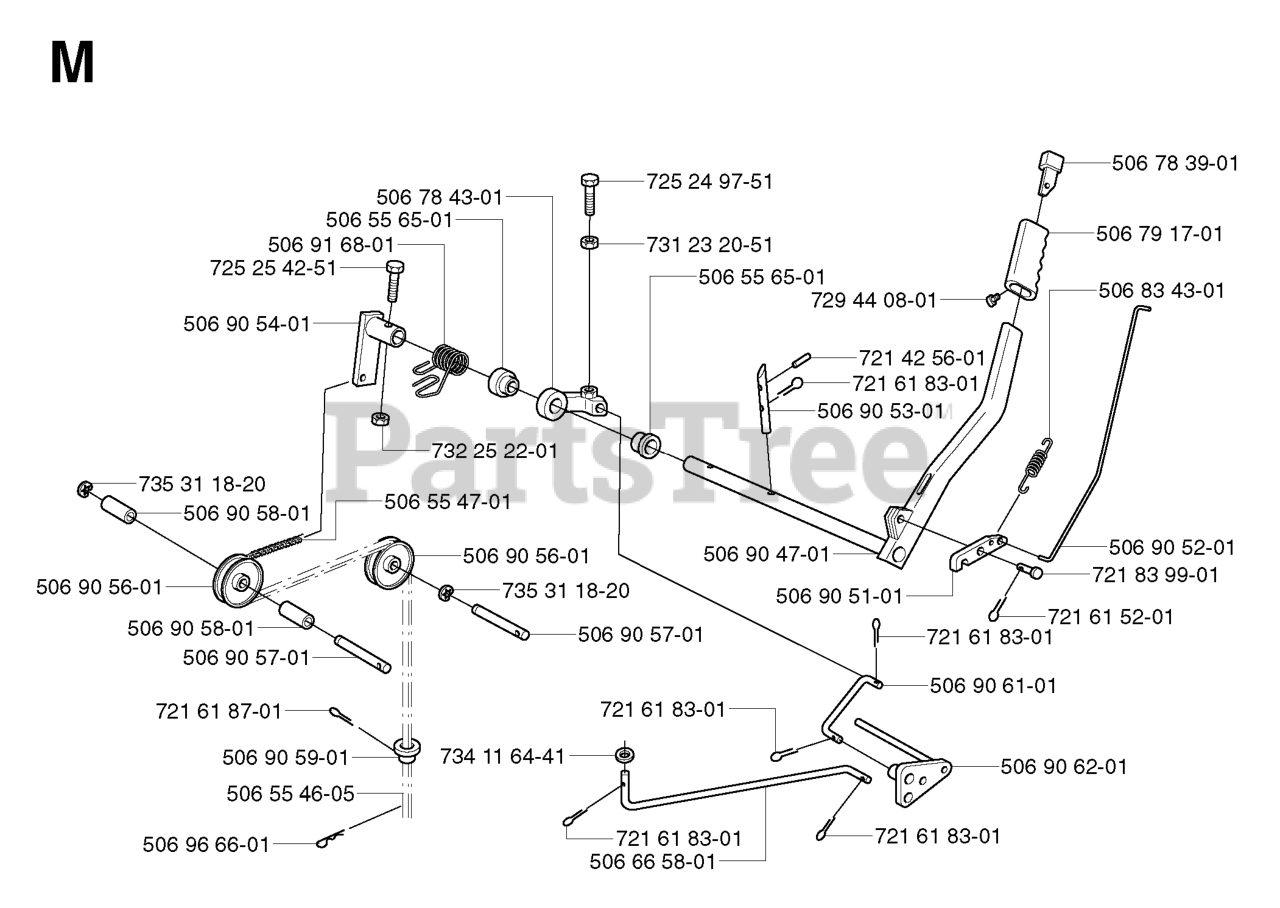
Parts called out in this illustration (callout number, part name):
1	STEERING WHEEL
2	AXLE ASSY
3	SPINDLE.ASM.LH.15"TIRES
4	SPINDLE.ASM.RH.15"TIRES
5	THRUST WASHER
9	BRNG T
10	DRAGLINK.15".TIRES
11	WASHER, LOCK 3/8
13	TUBE, PIVOT AXLE
15	NUT
17	SHAFT ASM STEERING
18	THRUST WASHER
19	STEERING SHAFT SUPPORT
22	SCREW.HX.WSH.HD
23	SHAFT ASSY PITTMAN
25	BRACKET STEERING
26	BUSHING.DRAGLINK (2 2)
27	GEAR.SECTOR
28	WASHER
29	SCREW 3/8-16X3/4
30	COTTER PIN
32	TIE ROD
36	BUSHING, STEERING
37	SCREW.TT.#10-32X.5.3/8.FLANGE
38	INSERT,STR WHEEL
39	WASHER 13/32 X 2-3/8 X 12GA
40	GRIPCO NUT
41	ADAPTER LT
42	BOOT STEERING
44	EXT SHAFT STEERING
46	CAP.SPINDLE.BLACK
47	ZERK M
51	NUT.71038.31-18.HEX.NYLOCK
54	BOLT.5/16-18X1-1/4 FULL.THREAD
62	STEERING KIT
65	SPACER BRACE AXLE
66	BEARING ARM
67	BOLT
68	BRACE.AXLE.15"TIRES
79	WASHER
80	BOLT.HX.NYLON3/8-16X
82	HOUR METER
85	FASTENER.XMAS.TREE
